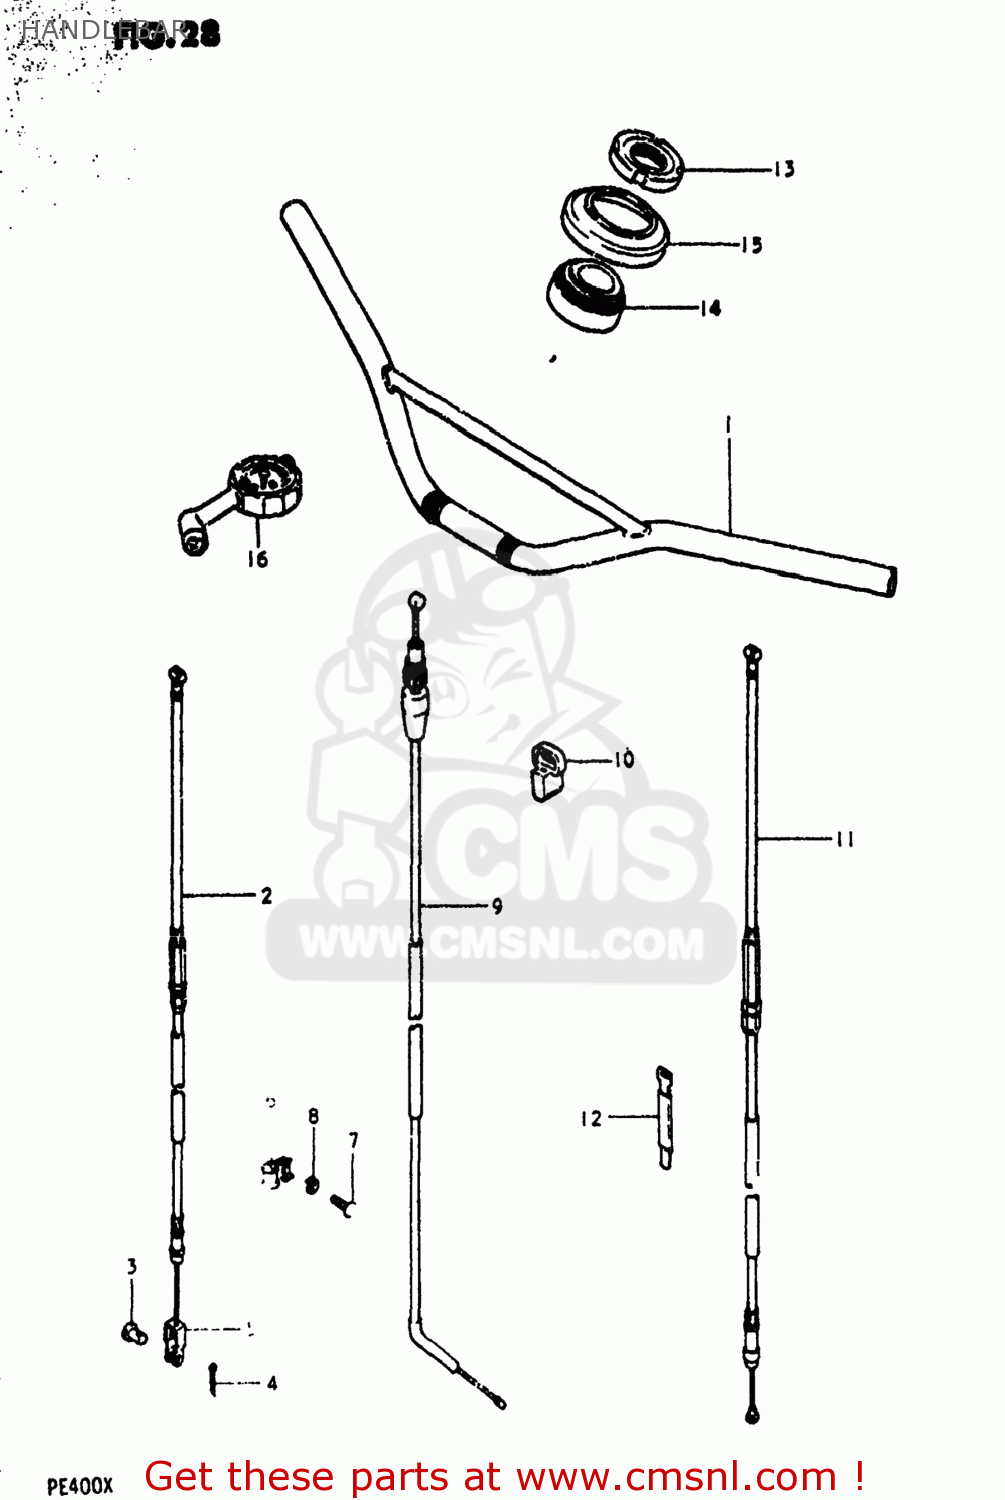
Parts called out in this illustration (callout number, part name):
1	HANDLEBAR
2	CABLE,FRONT BRAKE
3	PIN(L:13.5)
4	PIN
5	BRAKE CABLE HOOK
6	GUIDE,CABLE
7	SCREW
8	LOCK WASHER
9	CABLE ASSEMBLY,THROTTLE
10	GUIDE,CABLE
11	CABLE,CLUTCH
12	CLAMP
13	NUT,STEERING STEM(25X44X10)
14	TAPER,ROLLER BEARING
15	DUST SEAL,STEERING,UPPER
16	GAUGE ASSY,AIR PRESSURE
